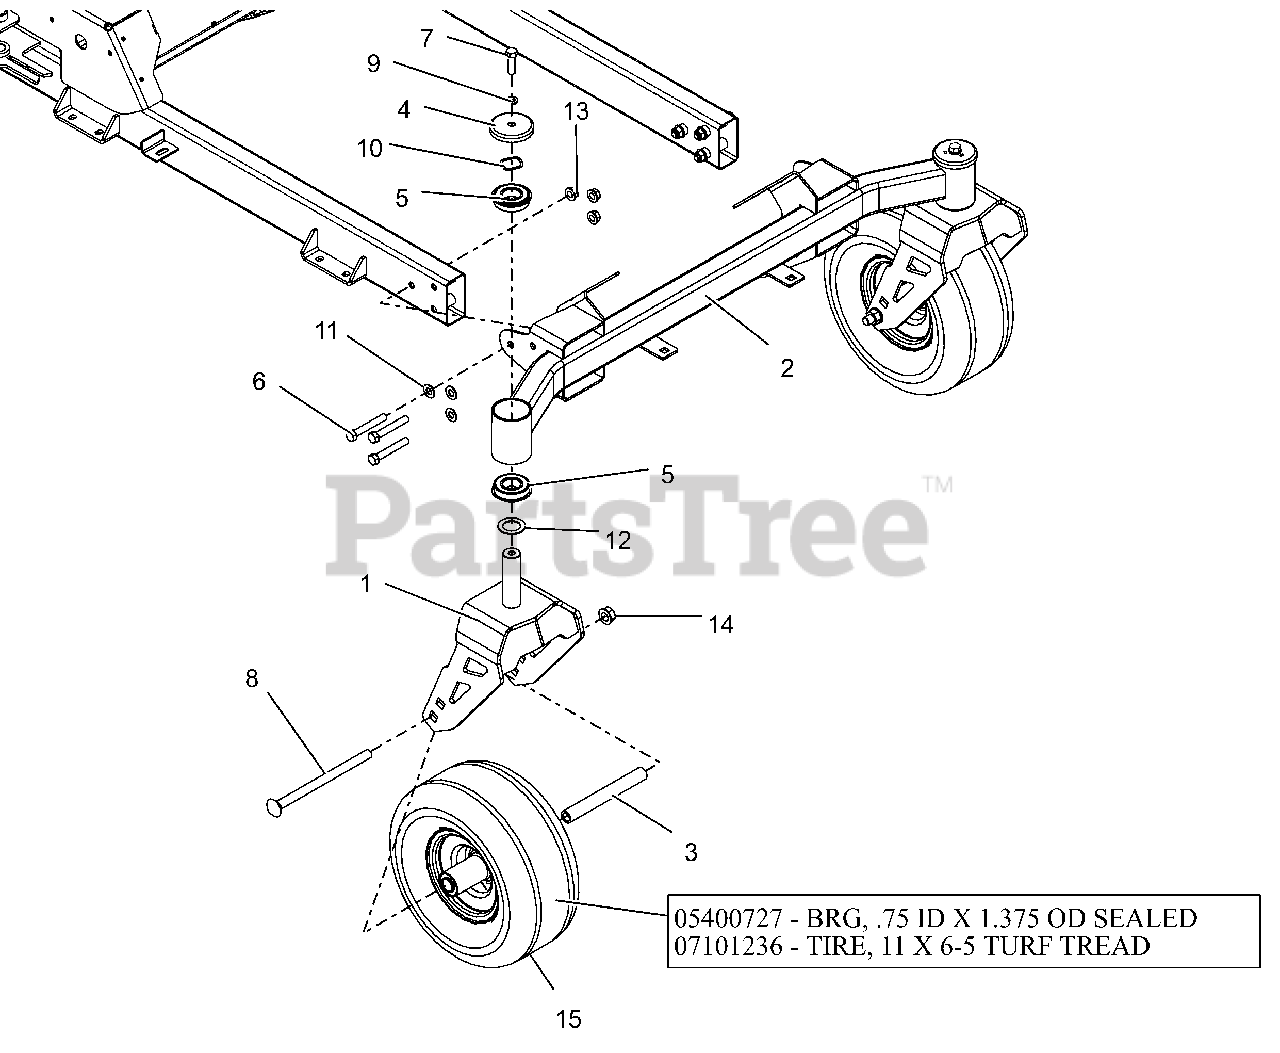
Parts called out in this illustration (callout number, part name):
1	WLDMT, CASTER FORK-XL (RED)
2	WLDMT, FRONT AXLE-X/XL (RED)
3	SPACER, FRONT WHEEL (WIDE 6.0)
4	SHIELD, AXLE BEARING
5	BEARING, BALL -2.000 OD X 1.000 ID X .5625 W/RING
6	BLT, HEX .38-16X2.50 G8 ZCC
7	BLT, HEX .38-16X1.25 G5 ZCC
8	BLT, RHSN .50-13X7.50 G5 ZCC
9	WSHR,LK-REG .375X.094 ZCC
10	WSHR-WAVE 1.0X1.25X.028 .145FH
11	WSHR-FL-STL 0.406X0.812X0.055 HRD
12	WSHR-HRD-THRS 1.007X1.542X.062
13	NUT-LK-TOP-FLG .375-16 GG ZCC
14	NUT-LK-TOP-FLG .500-13 GF ZCC
15	TIRE/WHEEL ASSY, 11X6-5
15	BRG, .75 ID X 1.375 OD SEALED
15	TIRE, 11X6-5 TURF TREAD
